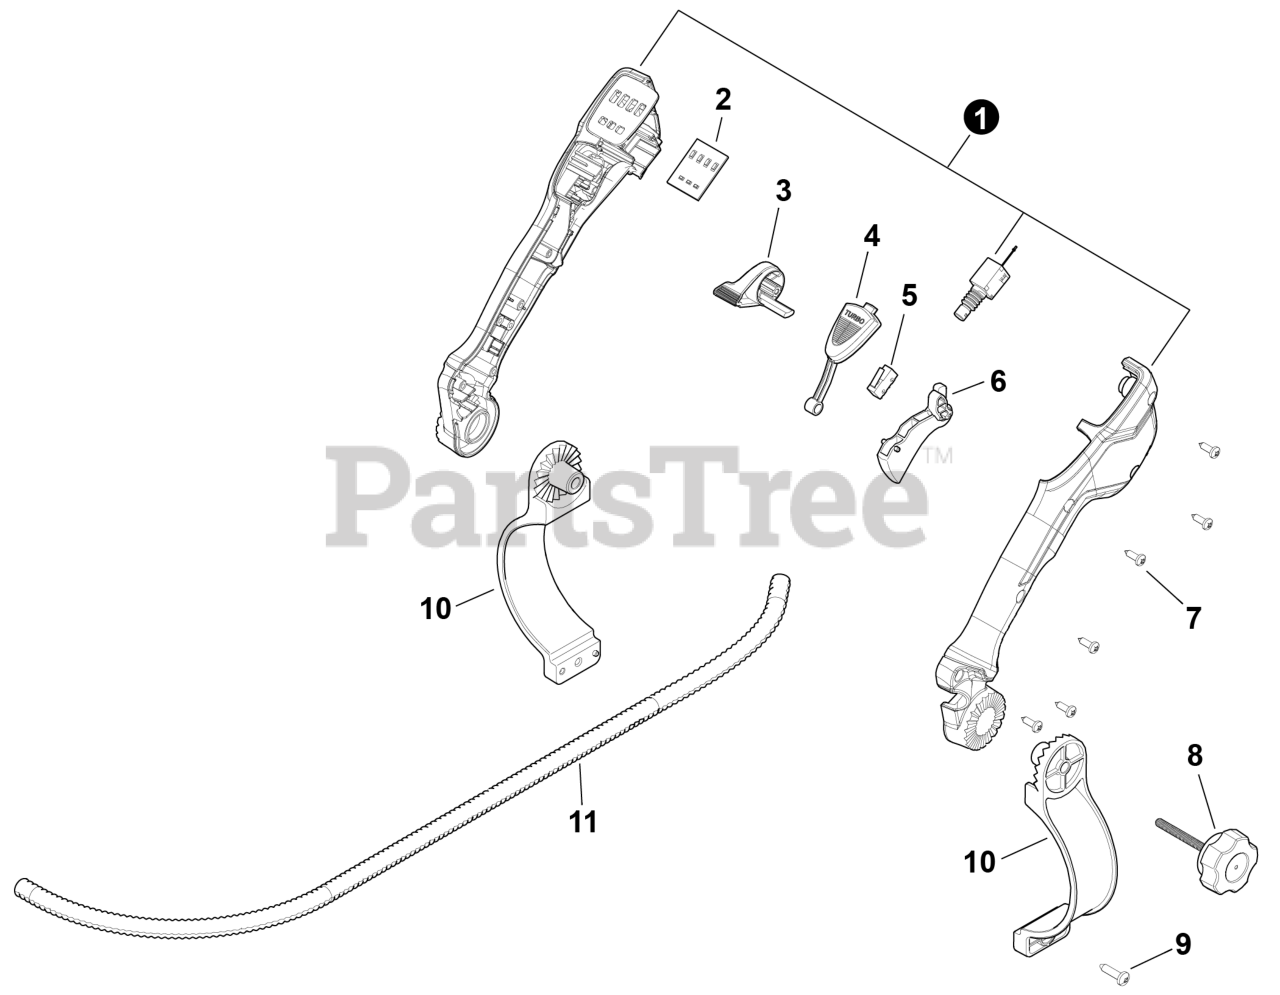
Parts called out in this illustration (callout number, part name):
1	HANDLE, CONTROL - SET
1	HANDLE, CONTROL - KIT
1	HANDLE,CONTROL-SET
2	DISPLAY, LED
3	KNOB, CRUISE CONTROL
4	BUTTON, TURBO
5	SWITCH, MICRO
6	SWITCH, SPEED CONTROL
6	LEVER, THROTTLE
7	LEVER, THROTTLE
8	SCREW, KNOB
9	SCREW, KNOB
10	CLAMP, THROTTLE MOUNT
11	CLAMP, THROTTLE MOUNT
11	HARNESS, WIRING
12	HARNESS, WIRING
